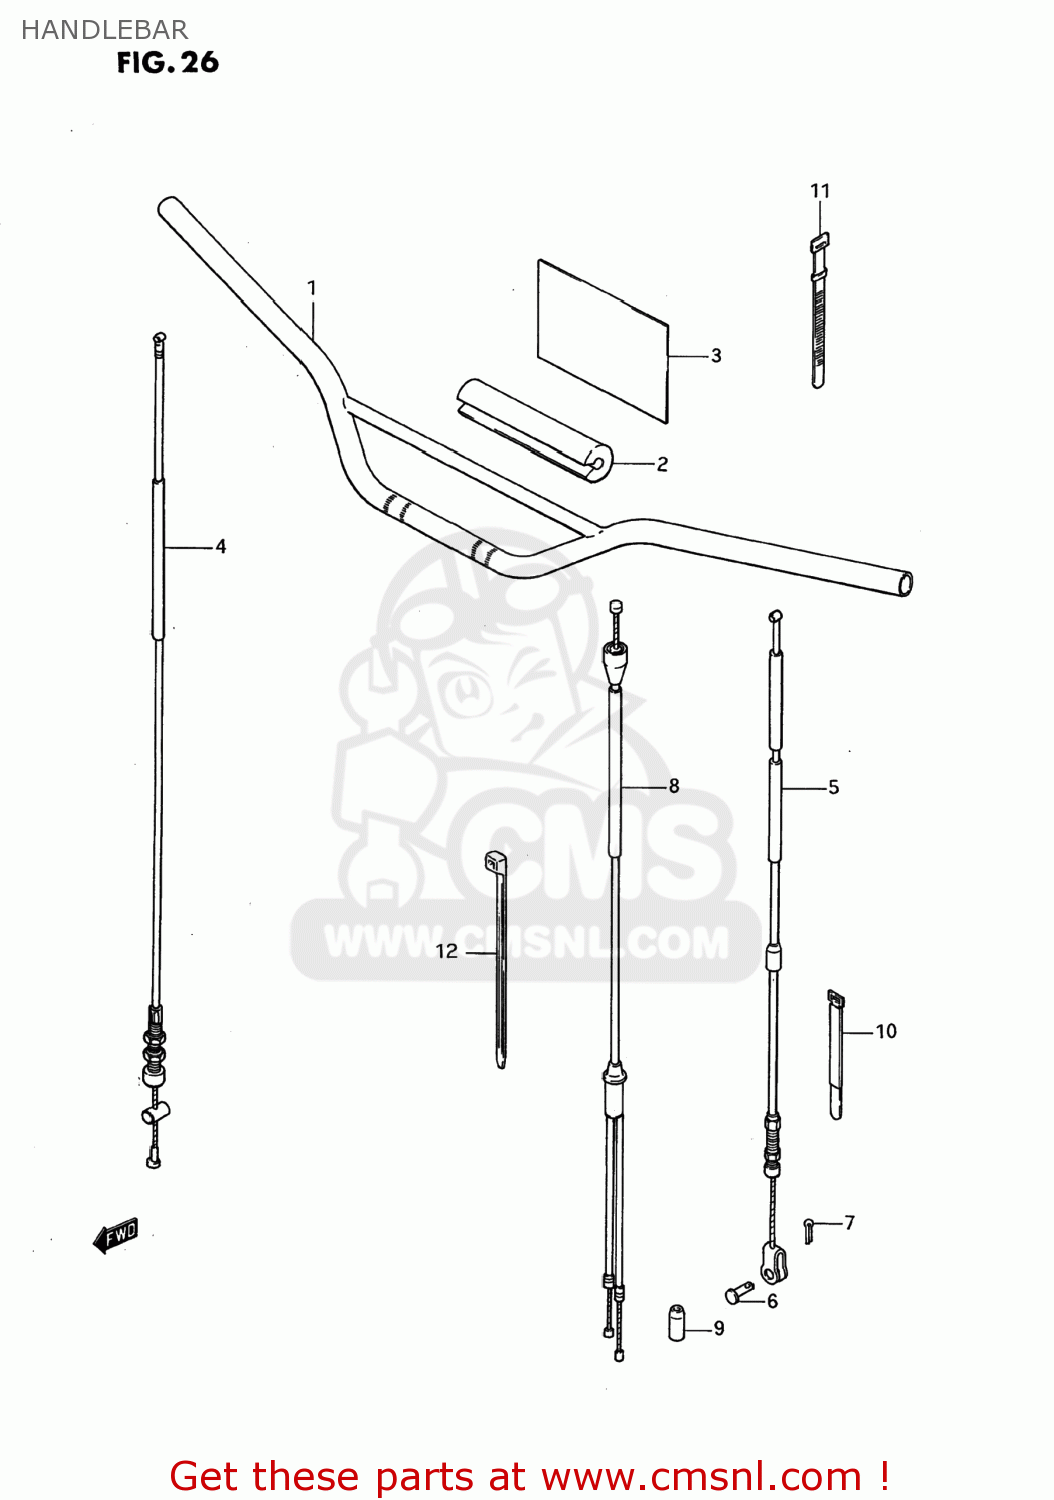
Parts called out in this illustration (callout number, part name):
1	HANDLEBAR
2	PAD,CROSSBAR
3	COVER,CROSS BAR PAD
4	CABLE,FR BRAKE
5	CABLE ASSY,CLUTCH
6	PIN(L:13)
7	PIN
8	CABLE ASSEMBLY,THROTTLE
9	SEAL,DUST(7X18X30)
10	CLAMP
11	CLAMP(L:145)
12	CLAMP L:165
